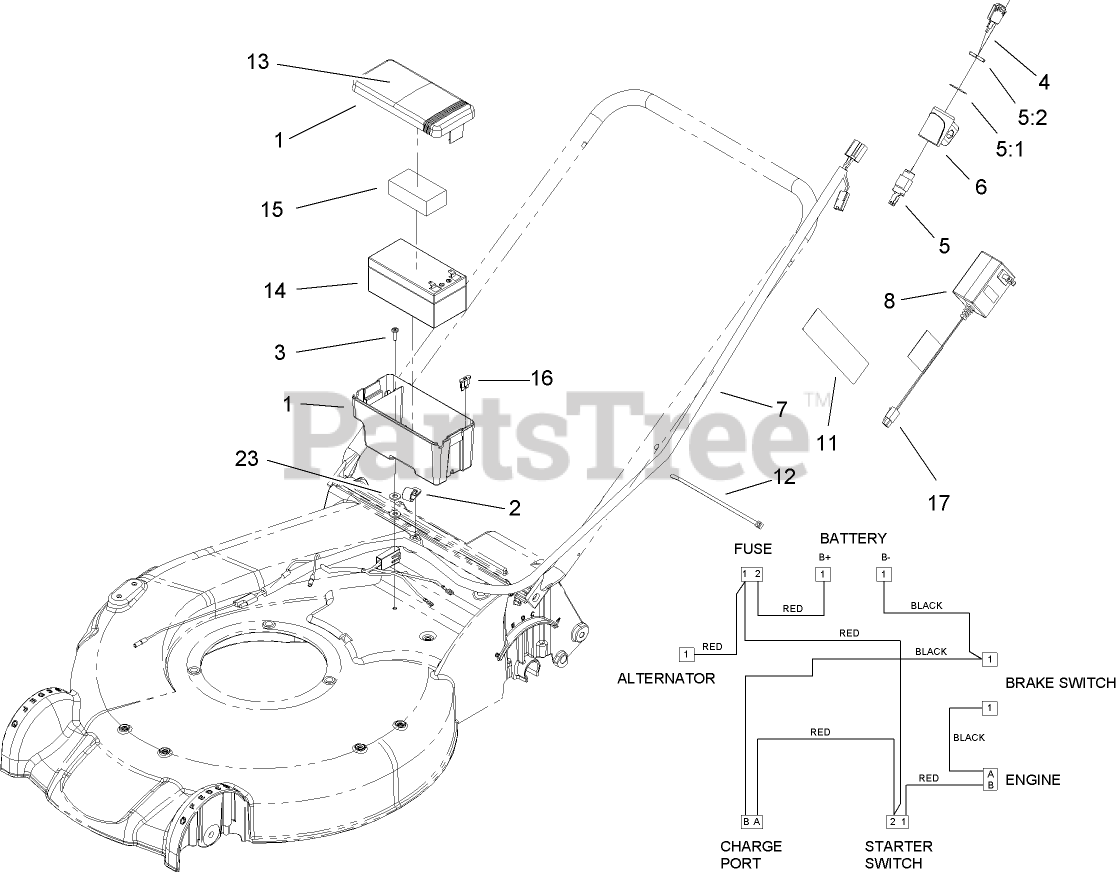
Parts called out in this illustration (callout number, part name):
1	BATTERY BOX ASM
2	CLAMP-R
5	STARTER SWITCH ASM
5:1	WASHER-LOCK
5:2	NUT-HH
6	MOUNT-SWITCH
7	HARNESS
8	CHARGER-EUROPEAN, 12V DC
11	DECAL-WARNING
12	TIE-CABLE
13	DECAL-INSTRUCTIONAL
14	BATTERY-WET
15	FOAM-BATTERY, TOP
16	FUSE-40 AMP
17	ADAPTER-CHARGER
23	WASHER-FLAT
